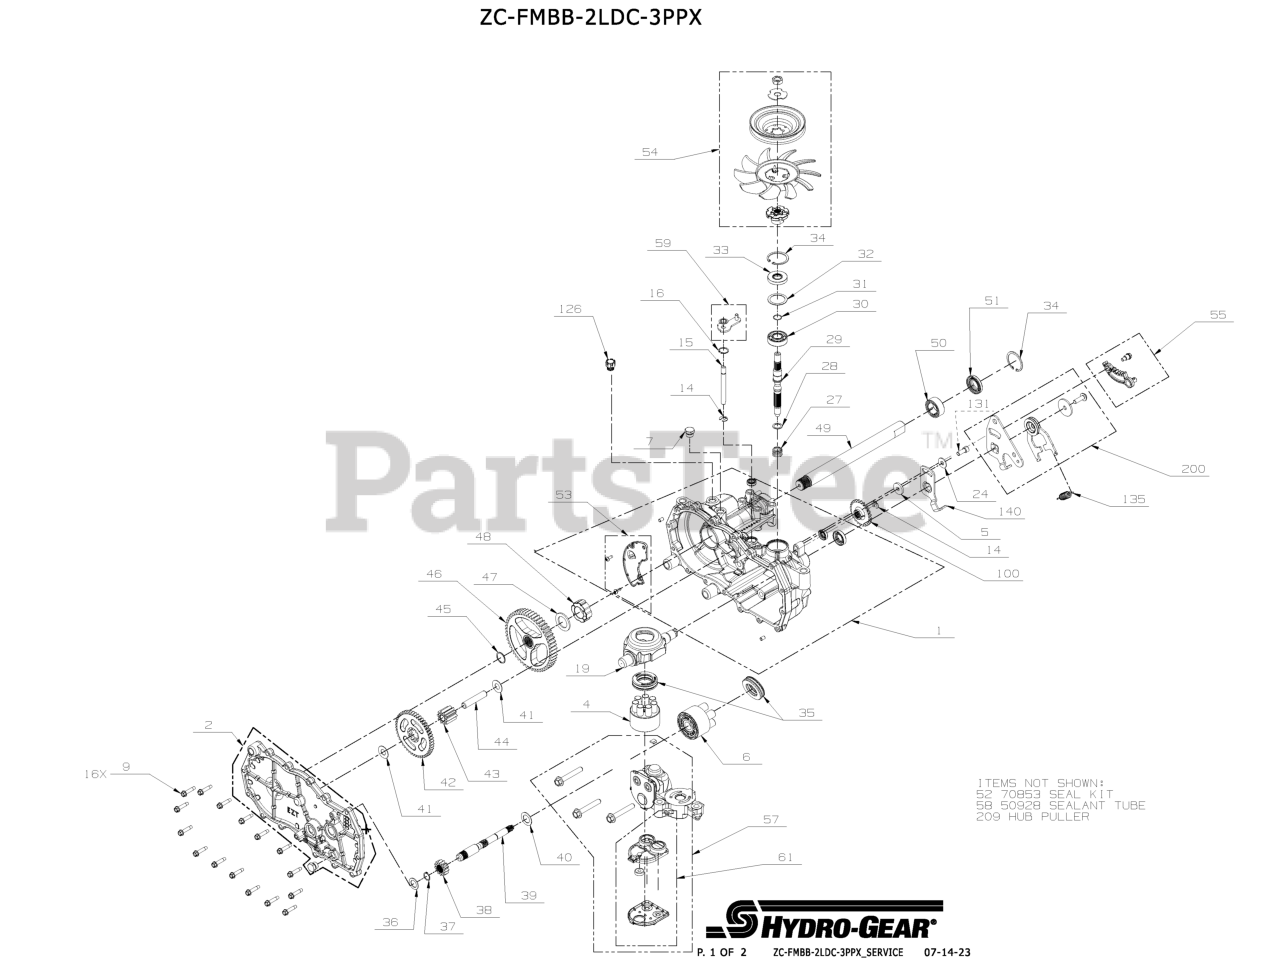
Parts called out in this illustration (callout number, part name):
1	KIT, HOUSING MAIN, LH
2	KIT, SIDE HOUSING, LH W/DRAIN
4	ASSY, BLOCK 7 PISTON
6	KIT, 10 CC BLOCK
7	PLUG EXT HEX VENT 9/16 18
9	SCREW,HEX WASHER 1/4-20X1.125
14	RING. RETAINING
15	ROD, BYPASS
16	RING, RET .750
19	TRUNNION, SWASHPLATE
27	SPRING. BLOCK
28	WASHER. THRUST .59 X .79 X .04
29	SHAFT, INPUT
30	BRG, BALL 17X40X12
31	RING, RET WIRE .561 ID
32	WASHER 1.23X1.56X.04
33	SEAL, LIP 17X40X7
34	RING, RET 1.56 INT
35	BEARING. THRUST 30 X 52 X 13
36	WASHER .63X1.0X.05
37	RING, RET 62 EXT
38	GEAR, 13T PINNION
39	SHAFT, MOTOR
40	WASHER .71 X 1.16 X .04
41	WASHER .5X1.0X.032
42	GEAR, 10T/48T
43	GEAR, 10T JACKSHAFT
44	PIN, JACKSHAFT
47	WASHER, 1.018 X 1.571 X .105 FLAT
48	BUSHING, SLEEVE (INBOARD)
49	SHAFT 1.00 X 11.7 D AXLE
52	KIT, SEALS AND RETAINING
53	KIT, EXPANSION PLATE LH
54	FAN PULLEY KIT 4.5X1.625
55	BRAKE ARM-RH, EZT
57	KIT, CENTER SECTION, W/FILTER - LH
58	SEALANT TUBE 10.1OZ.
59	KIT, BYPASS ARM
61	KIT, FILTER
100	DISC, COG BRAKE
126	ASSEMBLY, FITTING 9/16-18 BREATHER
131	KIT, RTN SCREWS
135	SPRING, EXTENSION
140	ARM, NEUTRAL LEFT
200	RING, RTNG .
209	HUB PULLER 5 BLT
